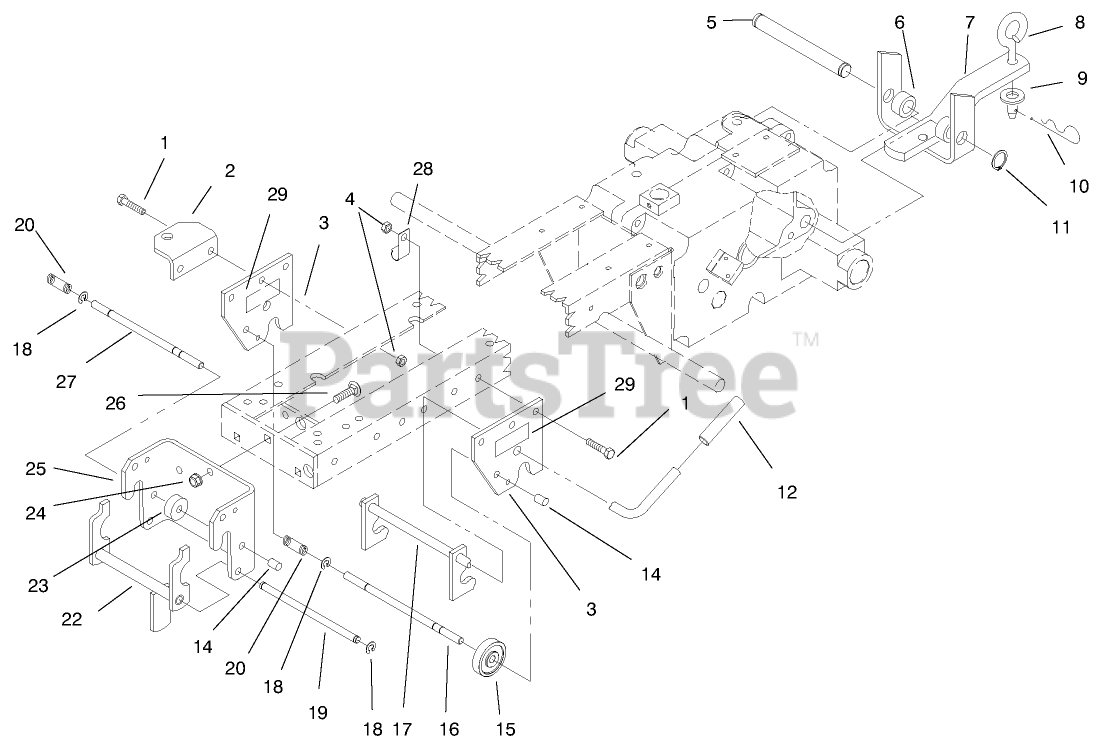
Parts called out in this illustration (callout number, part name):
1	SCREW-HH
2	SUPPORT
3	PLATE-HITCH
4	NUT-HEX
5	PIN-STATIONARY HITCH
6	SPACER
8	PIN-TOOL
9	WASHER-FLAT
10	PIN-HAIR
11	E-RING
12	GRIP
14	CAP-ROD, PLUNGER
16	ROD-LOCK
17	MID HITCH ASM
18	RING-RETAINING
19	ROD-LATCH PIVOT
20	SPRING
22	LATCH
24	NUT-LOCK, NI
25	HITCH-FRONT
26	BOLT-CARR
27	ROD-LOCK
28	CLIP
29	DECAL-ATTACH A-MATIC
